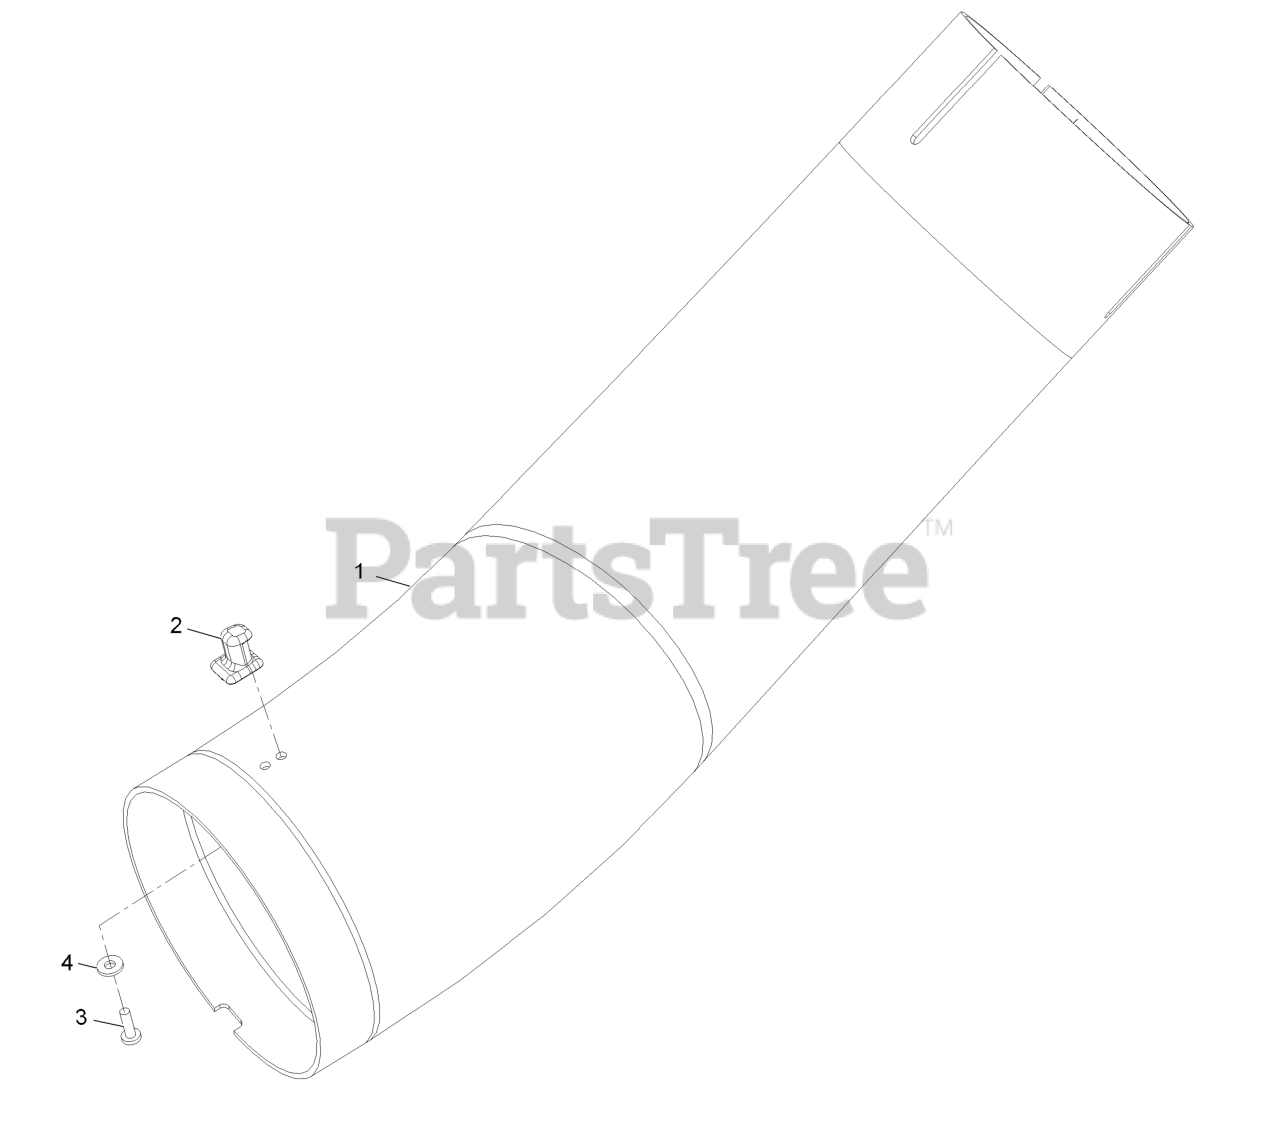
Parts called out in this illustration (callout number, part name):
1	Tube-Lower, Short
2	Latch-Keeper
3	Screw-PPH #10-24 X 5/8
4	Washer-#10 Std
